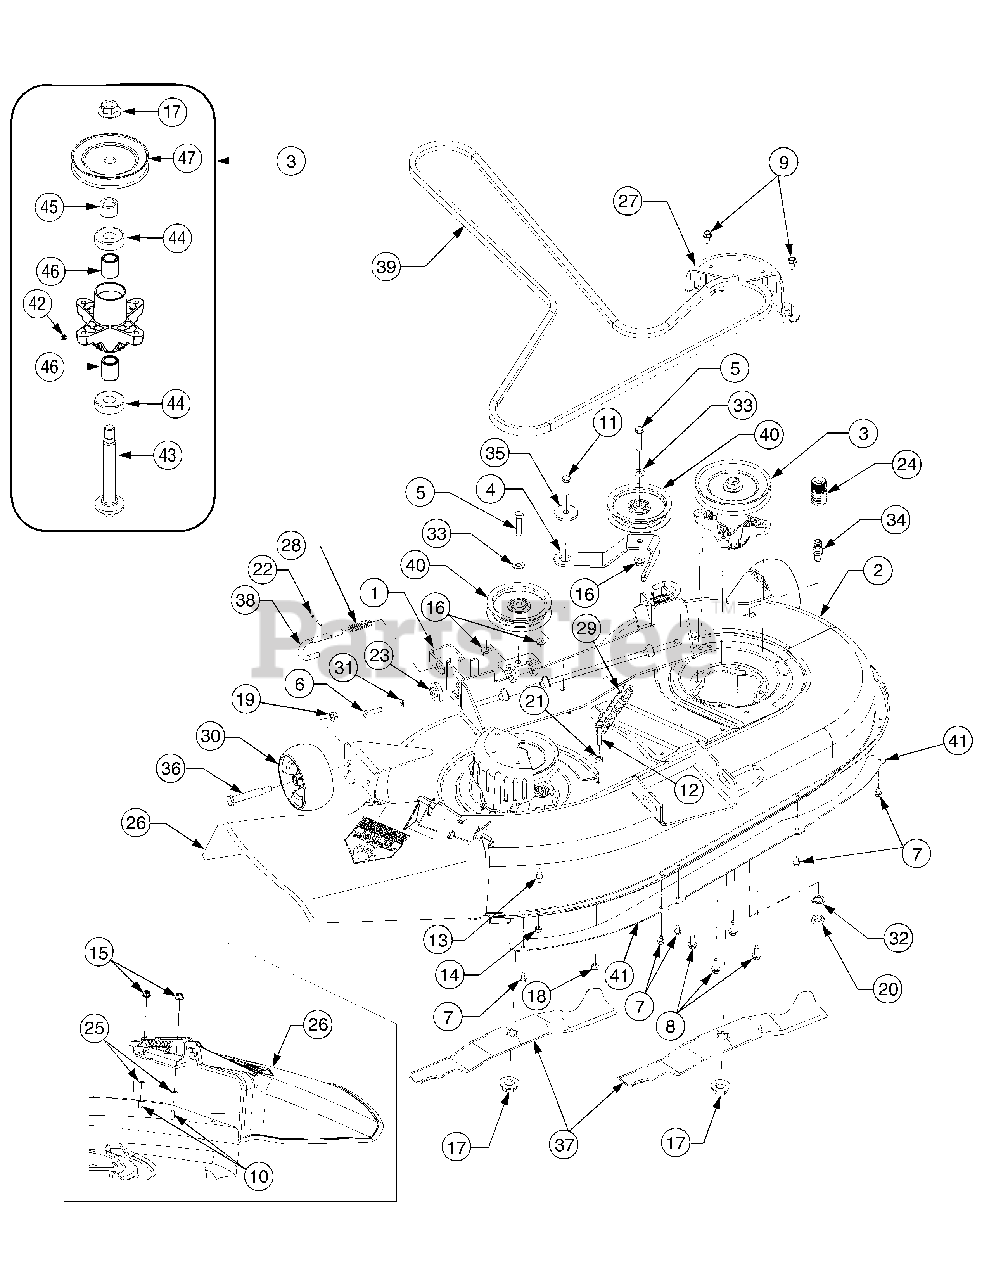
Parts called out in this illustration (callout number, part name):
3	Spindle Assembly
5	Screw, Hex Cap, 3/8-16 x 1.75 GR5
6	Screw, Hex Cap, 5/16-18 x 1.25 GR5
7	Screw, Hex Wash. Hd. Tapp 1/4-20 x .5
8	Screw, Hex Wash. Hd. Tapp 5/16-18 x .875
9	Screw, Hex Wash. Hd. Tapp 5/16-12 x .75
10	Screw, Hex Cap, 1/4-20 x .62 GR5 ..
11	Screw, Hex Cap, 3/8-16 x 1.25 GR5
12	Screw, Hex Cap, 5/16-18 x 1.75 GR5
13	Pin, Grass Catcher, 1/4-20
14	Nut, Hex Insert Lock, 1/4-20 GR8
15	Nut, Hx Insert Flange Lck, 1/4-20 GR5
16	Nut, Hx Insert Flange Lck, 3/8-16 GrF
17	Nut, Hex Flange, 5/8-18
18	Nut, Hex Insert Lock, 5/16-18 GR5 ..
19	Nut, Hex Flange Lock, 3/8-16 GrF
20	Nut, Hex, M16-1.5
21	Nut, Hex, 5/16-18 GR5
22	Pin, Cotter, 1/8 x 1.25
23	Gear, Deck Adjustment
24	Adapter, Water Nozzle
25	Nut, Push, .25 x .5
26	Chute Assembly, Discharge
28	Spring, Compression
29	Spring, Extension, .94 Dia. x 6.74
30	Wheel, Deck Ball, 5.0
31	Washer, Lock, 5/16
32	Washer, Internal Tooth Lock, 5/8
33	Washer, Flat, .38 x .93 x .11 HT
34	Nozzle, Deck Water
35	Spacer, Shoulder, .884 x .19
36	Screw, Shoulder, .5 x 2.5:3/8-16
37	Blade, 3 in 1, 21.23
38	Rod, Deck Hanger
39	Belt, V, Type A Sec x 114.1
40	Pulley, Idler, 4.25 Dia.
42	Fitting, Lube
43	Shaft, Spindle, 5.75
44	Bearing, Ball
45	Spacer, .820 x 1.15 x .73
46	Spacer, .8 x 1.10 x 1.322
47	Pulley, Deck, 6.3 Dia
